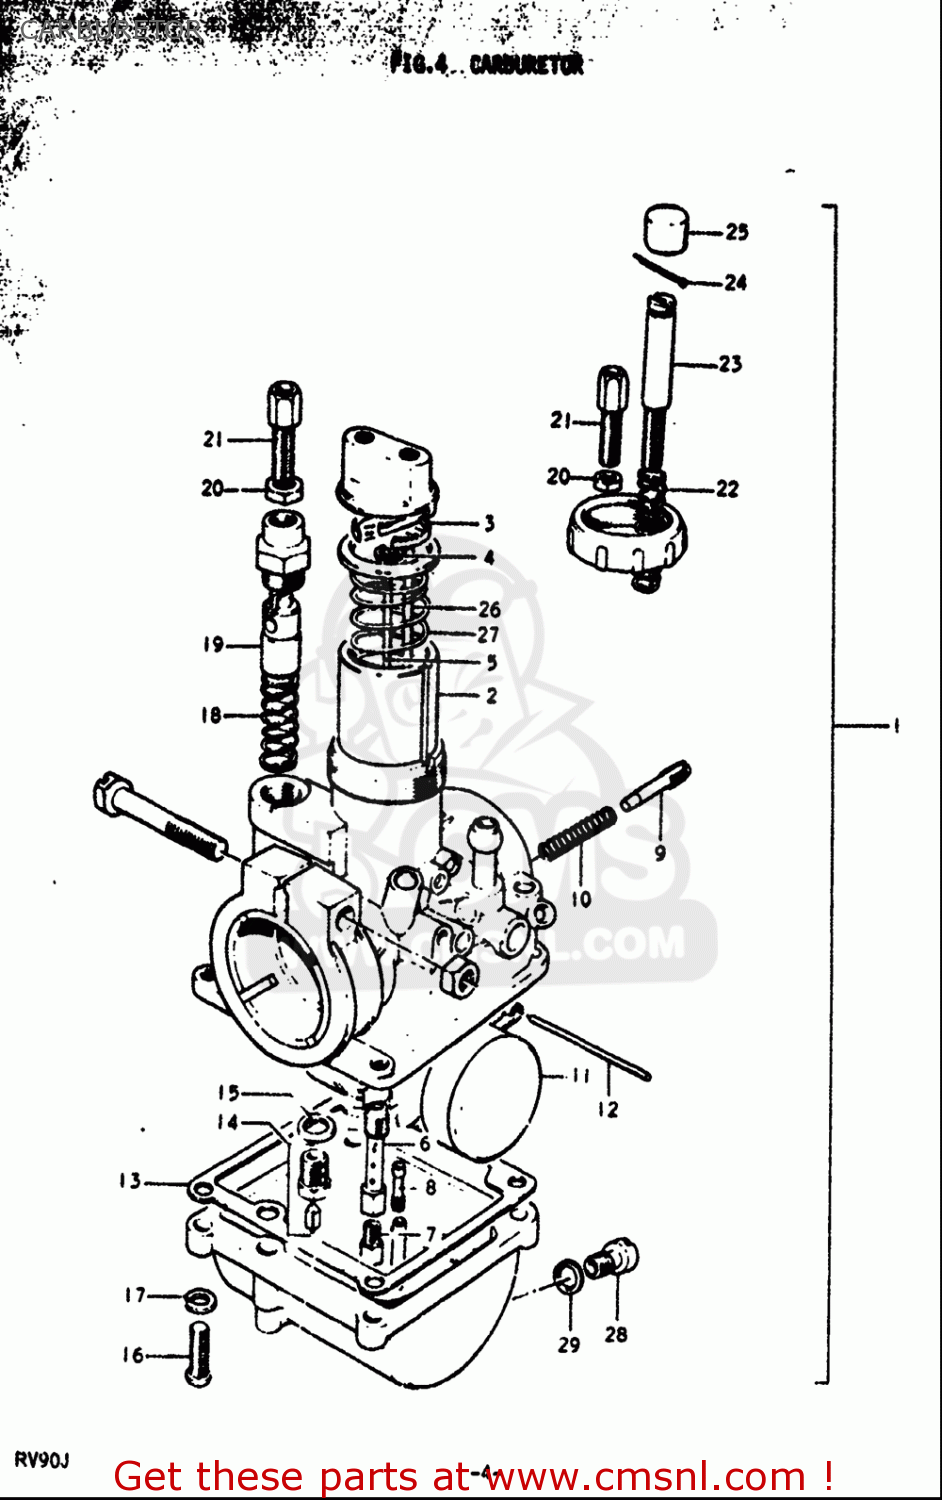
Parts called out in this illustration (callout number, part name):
1	CARBURETOR ASSY
3	STOPPER,NEEDLE CLIP
4	CLIP,NEEDLE
5	NEEDLE,JET
7	JET,MAIN(250)
8	JET,PILOT(17.5)
9	SCREW,PILOT AIR
10	SPRING
11	FLOAT
12	PIN,FLOAT
13	GASKET,FLOAT CAHMBER (NAS)
14	VALVE ASSY,NEEDLE
15	GASKET,NEEDLE VALVE (NAS)
16	SCREW 4X16
17	WASHER,LOCK
18	SPRING
19	PLUNGER,STARTER
20	NUT
21	ADJUSTER,CABLE
22	SPRING,THROTTLE SCREW
23	SCREW,THROTTLE STOP
24	PIN 12X10
25	CAP,THROTTLE VALVE STOP SCREW
26	ROD,THROTTLE VALVE ADJUST
27	SPRING,THROTTLE VALVE
28	PLUG
29	GASKET,DRAIN,PLUG (NAS)
